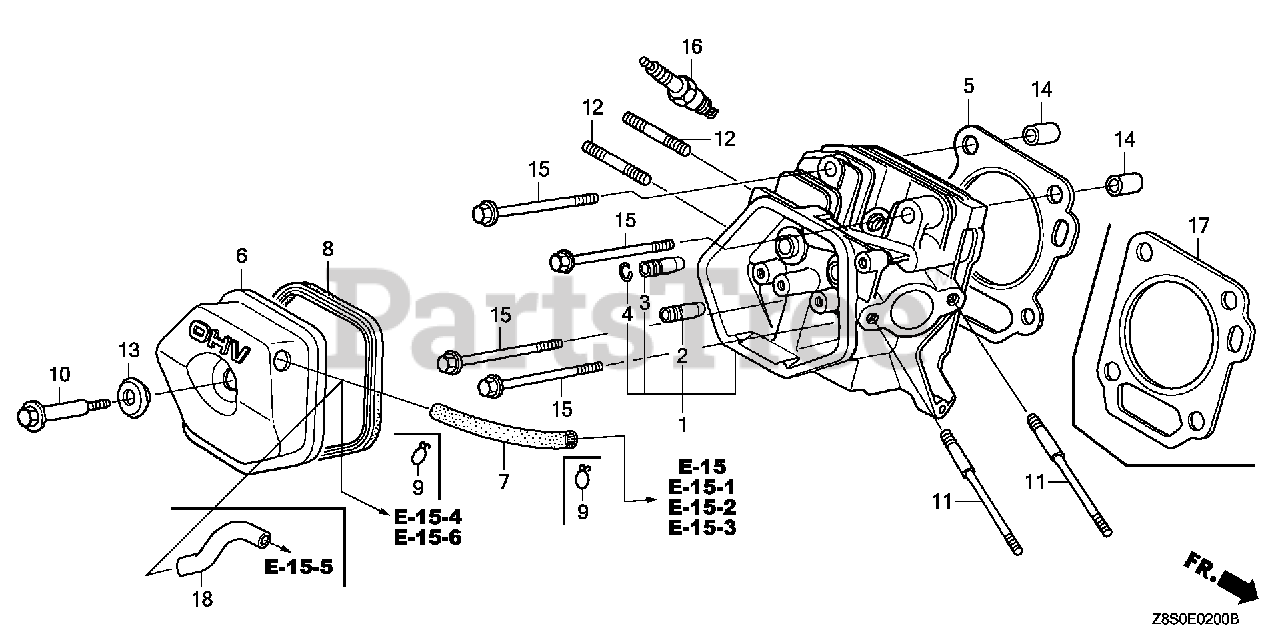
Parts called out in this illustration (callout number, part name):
1	CYLINDER HEAD
2	GUIDE, VALVE (OVER SIZE)
3	GUIDE, EX. VALVE (OVER SIZE)
4	CLIP, VALVE GUIDE
6	COVER, HEAD
6	COVER, CYLINDER HEAD
8	GASKET, HEAD COVER
10	BOLT, HEAD COVER
11	BOLT, STUD (8X123)
12	BOLT, STUD (8X32)
13	WASHER, HEAD COVER
14	PIN, DOWEL (12X20)
15	BOLT, FLANGE (10X80)
16	SPARK PLUG (BPR5ES) (NGK)
16	SPARK PLUG (W16EPR-U) (DENSO)
16	SPARK PLUG (BPR6ES) (NGK)
16	SPARK PLUG (W20EPR-U) (DENSO)
17	GASKET, CYLINDER HEAD
18	TUBE, BREATHER
